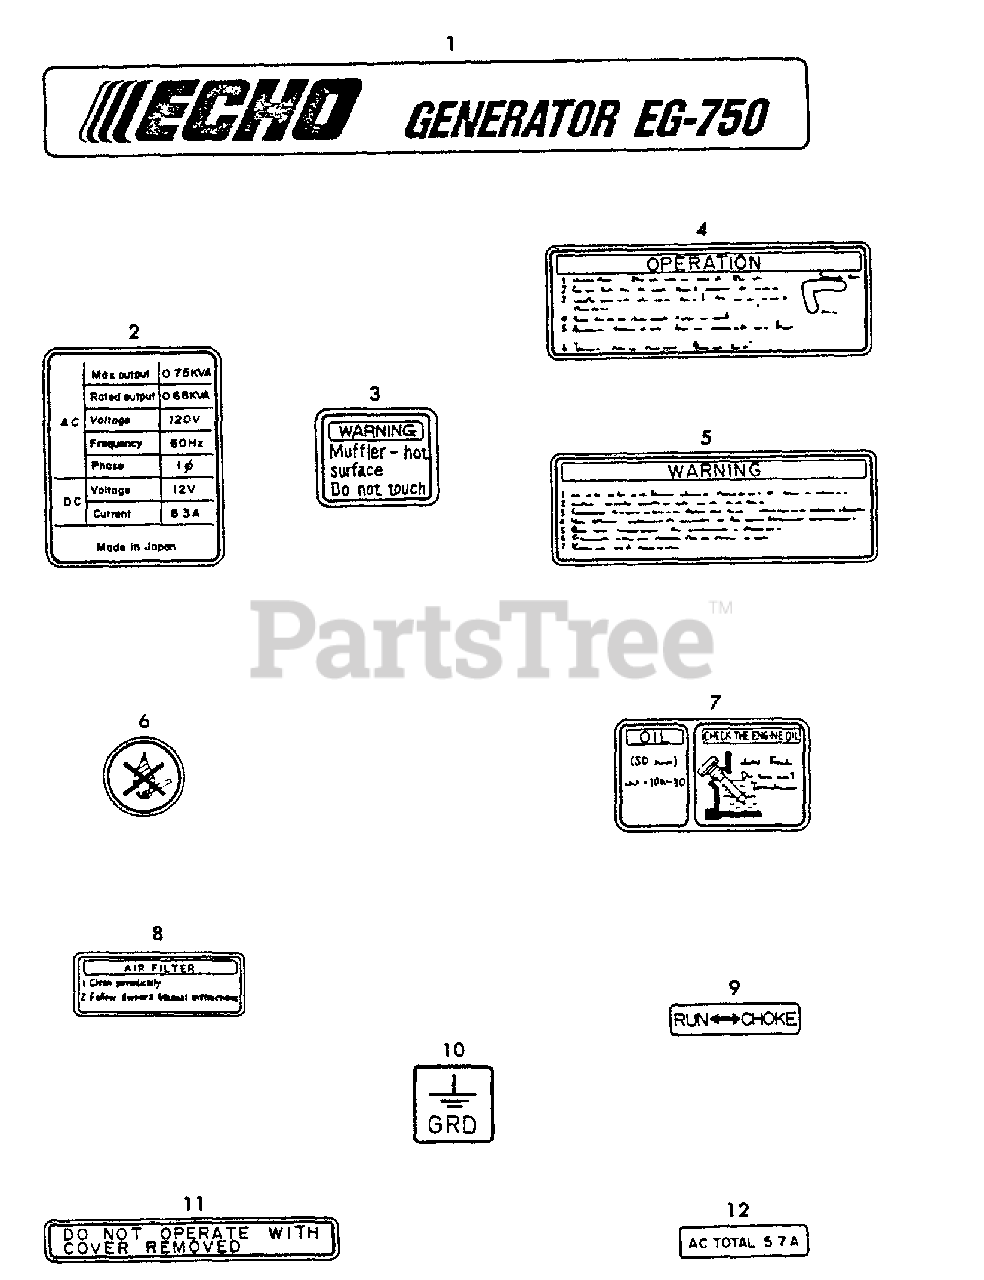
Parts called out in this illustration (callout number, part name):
1	LABEL - MODEL EG750
2	LABEL - GENERATOR
3	LABEL - CAUTION
4	LABEL - CAUTION -- OPERATION
5	LABEL - WARNING
6	LABEL - NON FIRE
7	LABEL - OIL
8	LABEL - AIR CLEANER
9	LABEL - CHOKE
10	LABEL - GROUND
11	LABEL - CAUTION
12	LABEL - AMPERE
